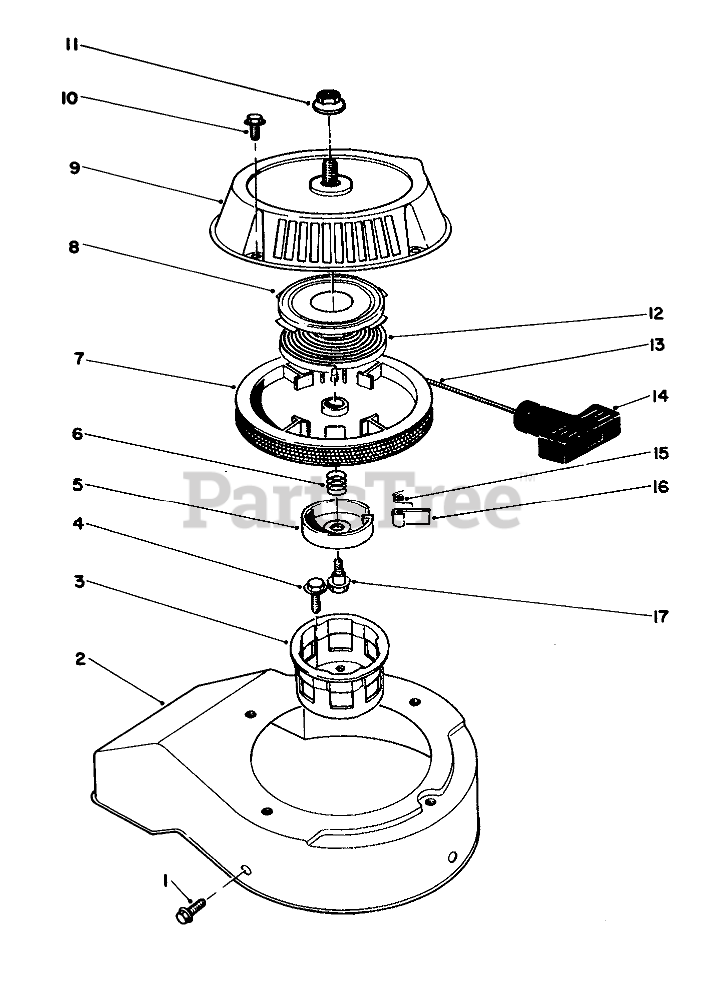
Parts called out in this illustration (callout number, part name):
2	BLOWER SHROUD
3	CUP - STARTER
4	WASHER-FLAT HD, TREATED
5	RETAINER
6	SPRING
8	Retainer-Recoil Spring
9	RECOIL CASE
10	MOUNTING SCREW
11	NUT (F/W & PPP)
12	Spring-Recoil (Incl. Ref. #8)
13	ROPE-STARTER
14	HANDLE-RECOIL
15	SPRING
